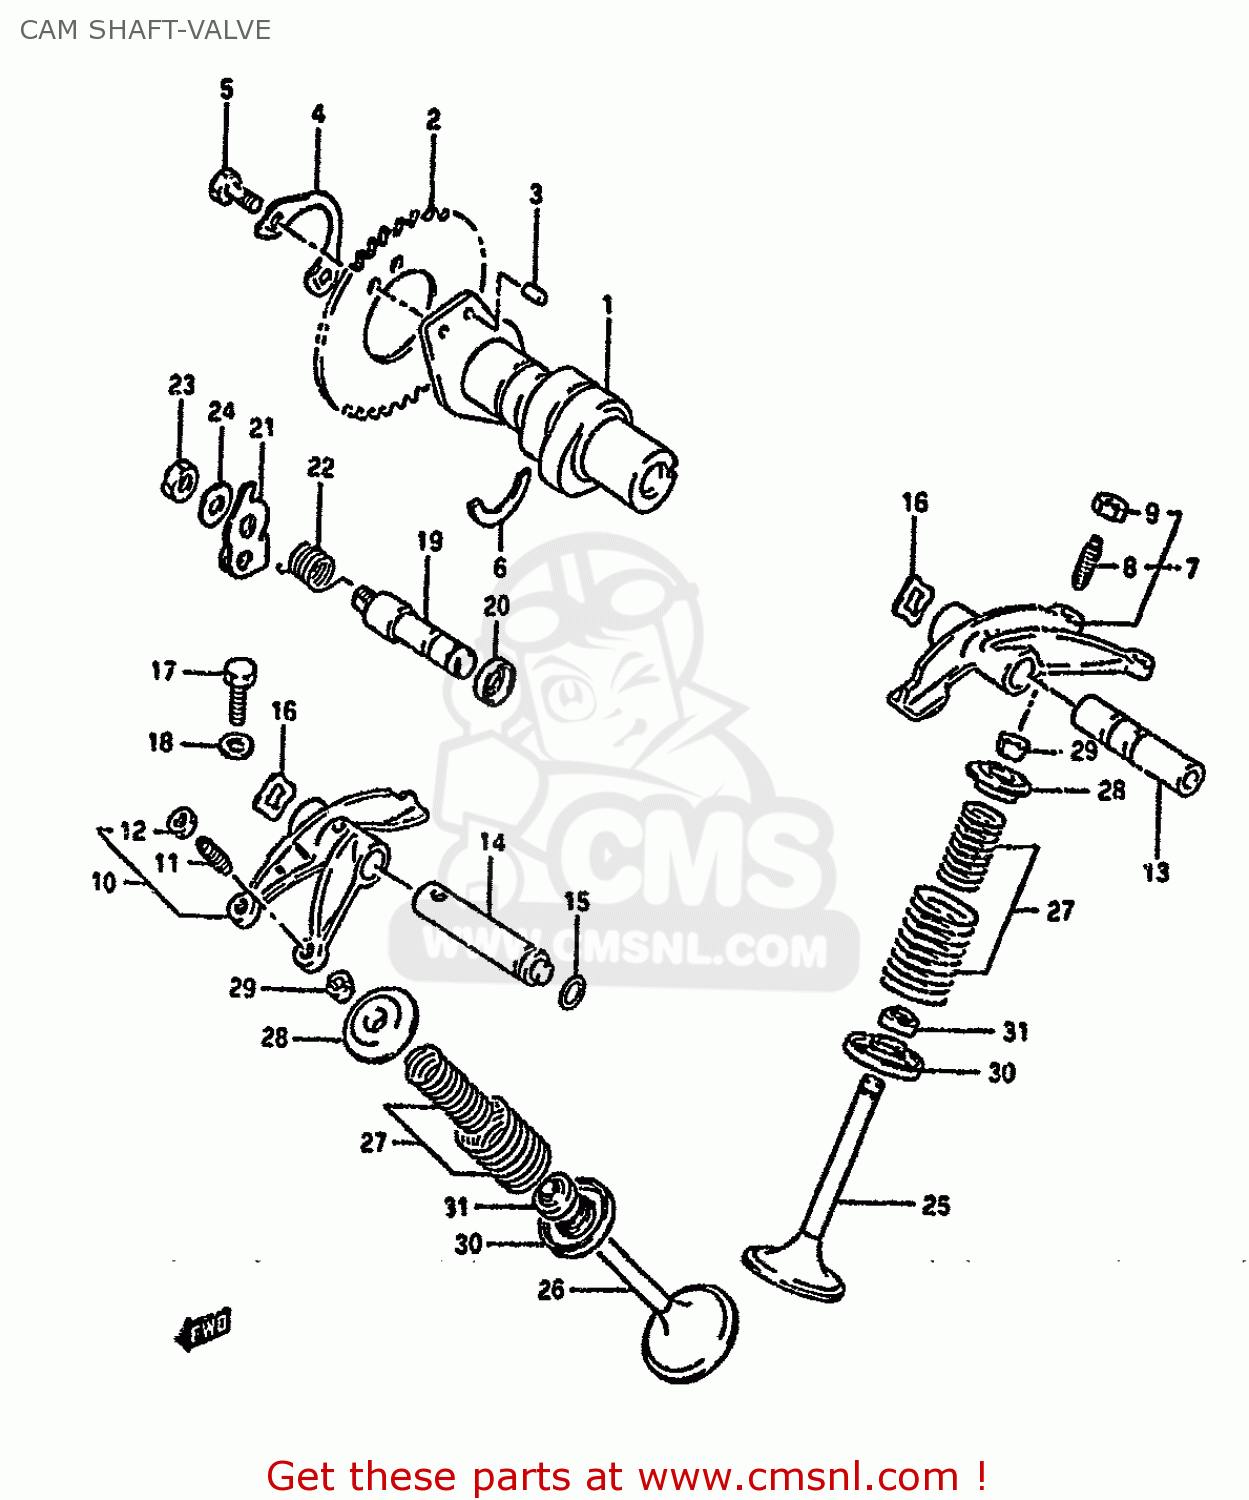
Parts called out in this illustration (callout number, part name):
1	CAMSHAFT
2	SPROCKET,CAMSHAFT(NT:42)
3	PIN
4	WASHER,CAM CHAIN SPROCKET
5	BOLT(6X12.5)
6	C RING
7	ARM,VALVE ROCKER INTAKE
8	SCREW,TAPPET ADJUSTING
9	NUT,ADJUSTING SCREW
10	ARM,VALVE ROCKER EXHAUST
11	SCREW,TAPPET ADJUSTING
12	NUT,ADJUSTING SCREW
13	SHAFT,VALVE ROCKER ARM INTAKE
14	SHAFT,EXHAUST VALVE ROCKER ARM
15	O RING(D:1.9,ID:8.6)
16	WASHER
17	BOLT 6X30
18	GASKET(5.8X13X1.2) (NAS)
19	SHAFT,DECOMPRESSION
20	SEAL,OIL(10X17X6)
21	LEVER,DECOMP SHAFT
22	SPRING,DECOMPRESSION SHAFT LEVER
23	NUT
24	WASHER
25	VALVE,INTAKE
26	VALVE,EXHAUST
27	SPRING SET,VALVE
28	RETAINER,VALVE SPRING
29	COTTER VALVE
30	SEAT,VALVE SPRING
31	SEAL,OIL(7X14.4X9)
